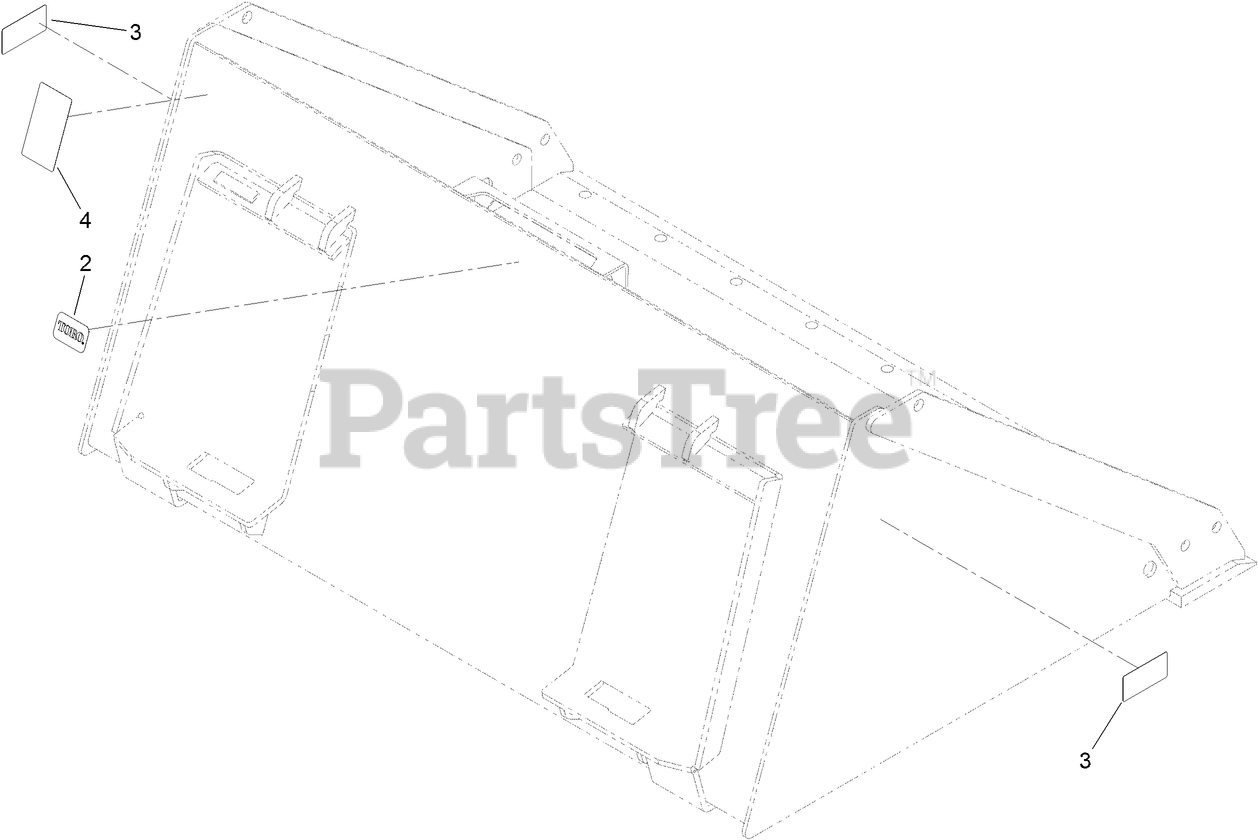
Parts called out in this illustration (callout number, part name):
2	DECAL
3	DECAL-DANGER
4	DECAL-WARNING, CAPACITY
